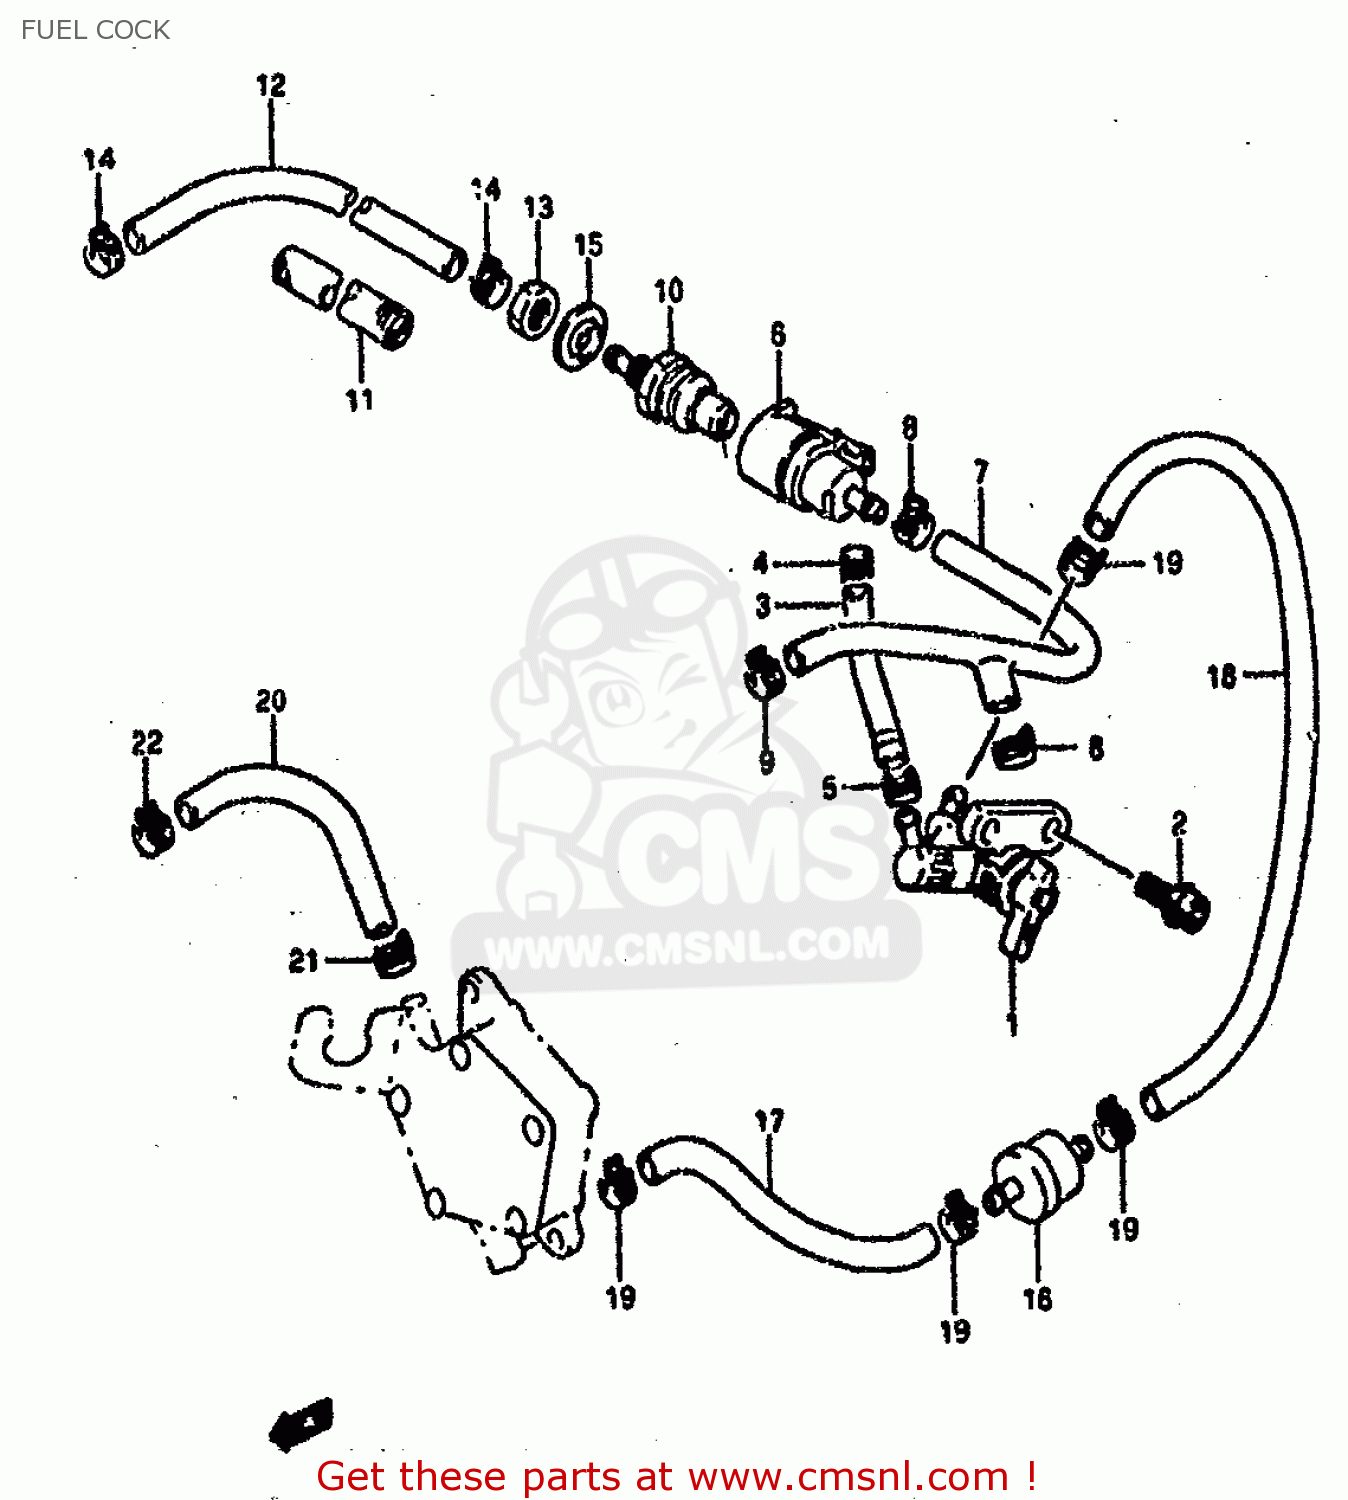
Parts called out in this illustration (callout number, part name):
1	COCK ASSY,FUEL
2	BOLT
3	HOSE,FUEL ON
4	CLIP
5	CLIP
6	SOCKET,FUEL HOSE LH
7	HOSE,FUEL 3WAY
8	CLIP
9	CLIP
10	PLUG
11	HEATSHIELD,FUEL HOSE
12	HOSE,FUEL JOINT,R
13	NUT
14	CLIP
15	WASHER
16	FILTER,FUEL
17	HOSE,FUEL FILTER & PUMP
18	HOSE (7X12X300)
19	CLIP
20	HOSE,PUMP & CARB
21	CLIP
22	CLIP
